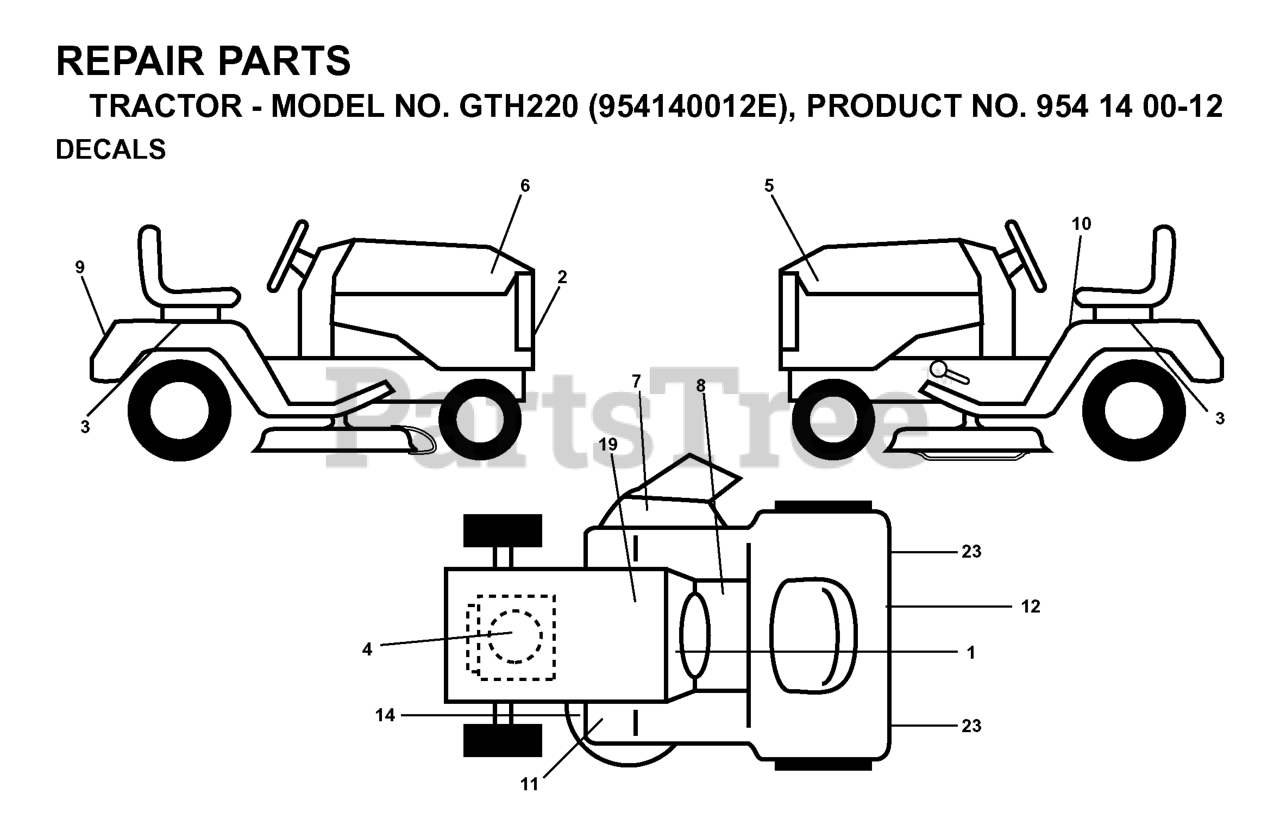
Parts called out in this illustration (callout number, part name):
2	DECAL.GRILLE.HUSQ
3	DECAL, FENDER
7	DECAL WARNING (ENGLISH/FRENCH)
8	DECAL PARK BRAKE
9	DECAL FENDER HUSQ
10	DECAL FENDER DANGER
14	DECAL V-BELT SCHEMATIC
19	DECAL BTRY SYMBOLS
23	REFLECTOR-TAIL YT
